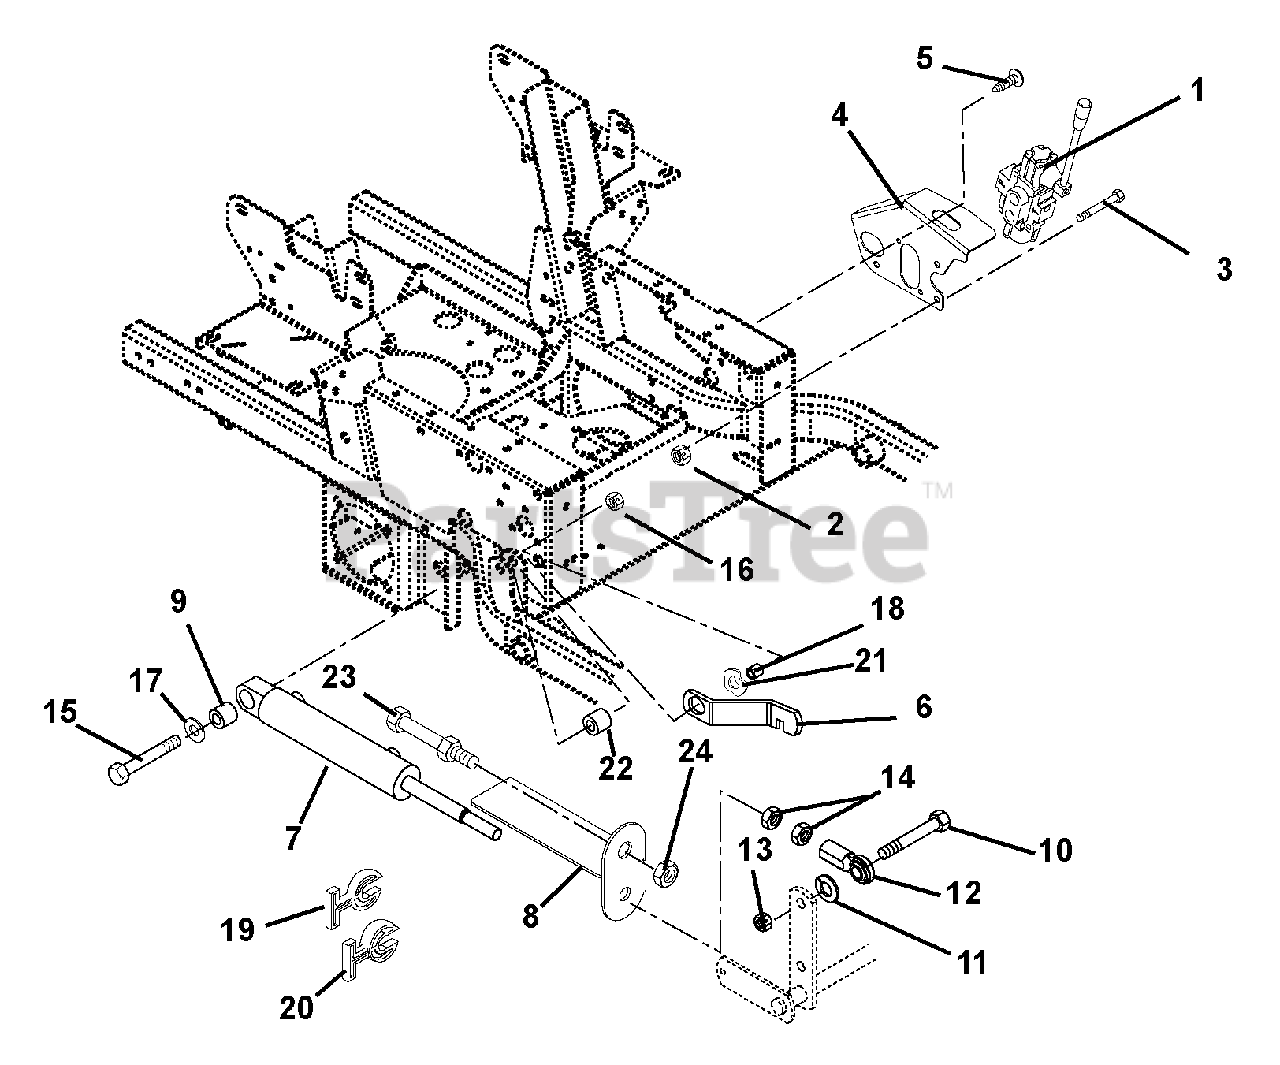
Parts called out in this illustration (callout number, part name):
1	Valve, Hydraulic
2	Nut, Locking Top Flange .31-18
3	Bolt, Hex .31-18 x 2.50 Grade 5
4	Valve Mounting Bracket
5	Screw, Tapping .38-16 x .50 Hex Washer Head
7	Cylinder, Lift
8	Strap, Cut Indicator/Guard
9	Bushing .516 x 1.00 x 1.050
10	Bolt, Hex .62-11 x 2.25 Grade 8
11	Washer, Lock .62 x .156
12	Rod End - Female - Right Hand .63
13	Nut, Locking Center .62-11
14	Nut, Jam .625-18
15	Bolt, Hex .50-13 x 3.50 Grade 5
16	Nut, Locking Top Flange .50-13
17	Washer, Flat Steel .515 x 1.625 x .25
18	Bushing, Flange .515 x .75 x .275 x 1.12
19	Stop, Cylinder .34 Thick
20	Stop, Cylinder .68 Thick
21	Washer, Wave .076 x 1.12 xz .08
22	Spacer .50 I.D. x .88 O.D. x .88
24	Nut-Jam .75-16
